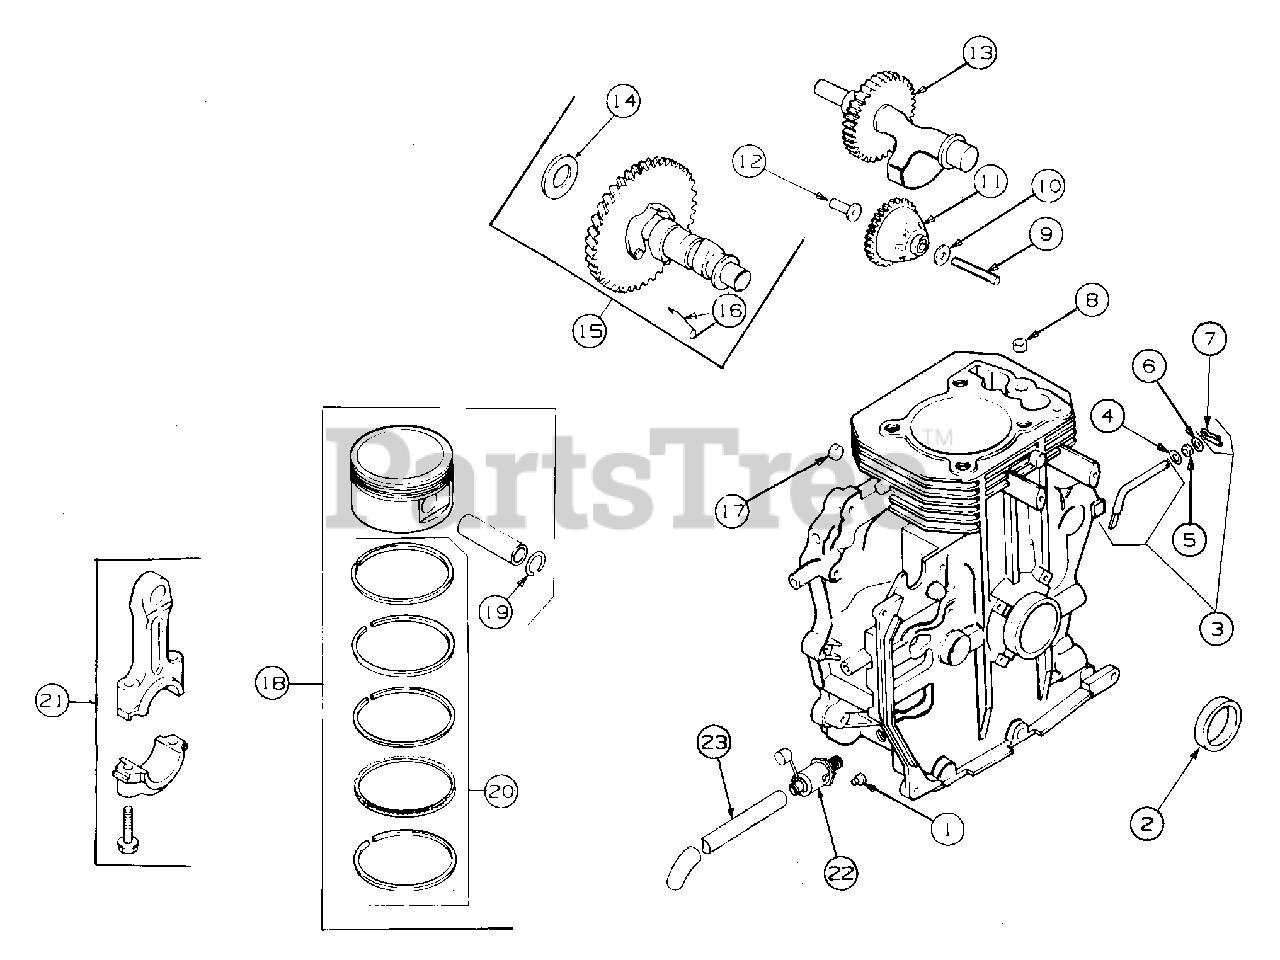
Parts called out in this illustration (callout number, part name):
1	Plug, Solid Sq. Head, 3/8 NPTF
2	Seal, Crankshaft
3	Kit, Gov. Cross Shaft
4	Washer, Governor Shaft, 6mm
5	Seal, Governor Cross Shaft
6	Washer, Plain, 1/4
7	Pin, Governor Hitch
8	Dowel, Locating
9	Shaft, Governor Gear
10	Washer, Governor Gear Thrust
11	Gear, Governor Assy
12	Pin, Governor Regulating
13	Shaft, Balance
14	Shim, Camshaft, .0280 (White)
15	Camshaft Assy,
16	Spring, Actuating
17	Plug, Cup
18	Piston w/Ring Set, Std
19	Retainer, Piston Pin
20	Ring Set, Std.
21	Rod, Connecting, Std
22	Drain, Oil
23	Hose, Oil Drain
